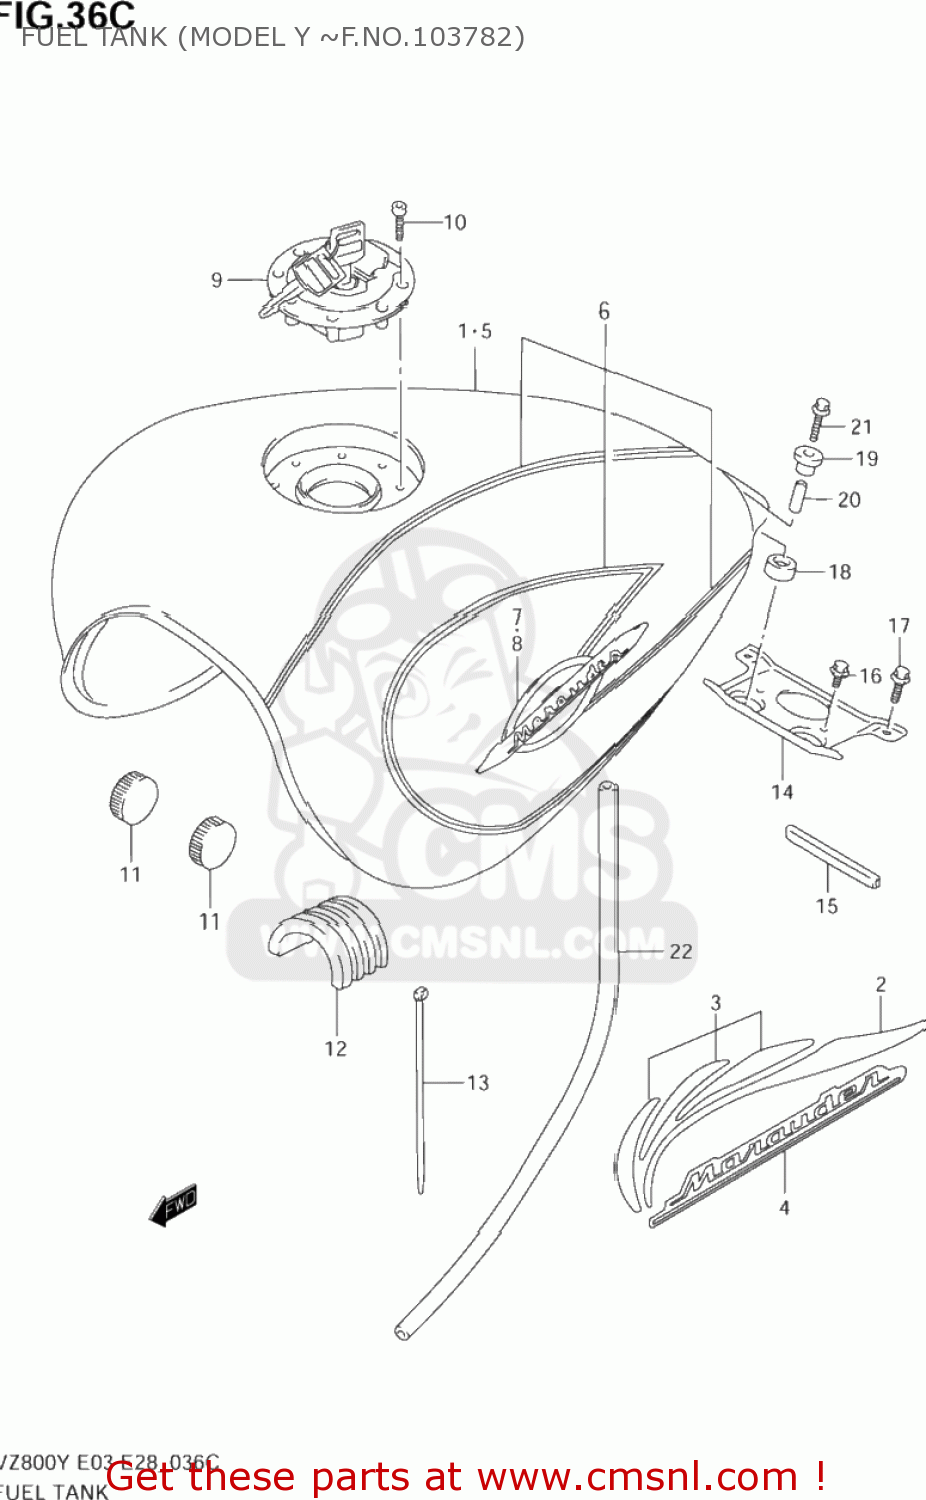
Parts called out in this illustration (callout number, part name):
1	TANK ASSY,FUEL(BLACK)
2	TAPE SET,FUEL TANK (SILVER)
3	EMBLEM SET,FUEL TANK
4	EMBLEM,FUEL TANK
5	TANK ASSEMBLY,FUEL
6	TAPE SET,FUEL TANK
7	EMBLEM,FUEL TANK,R
8	EMBLEM,FUEL TANK,L
9	CAP SET,FUEL TANK
10	BOLT(5X20)
11	CUSHION
12	CUSHION,FUEL TANK UPR
13	CLAMP(L:250)
14	BRACKET,FUEL TANK RR
15	PROTECTOR
16	BOLT
17	BOLT
18	CUSHION,FUEL TANK RR NO.2
19	CUSHION
20	SPACER(6.5X10.5X22.5)
21	BOLT
22	HOSE,FUEL TANK DRAIN
